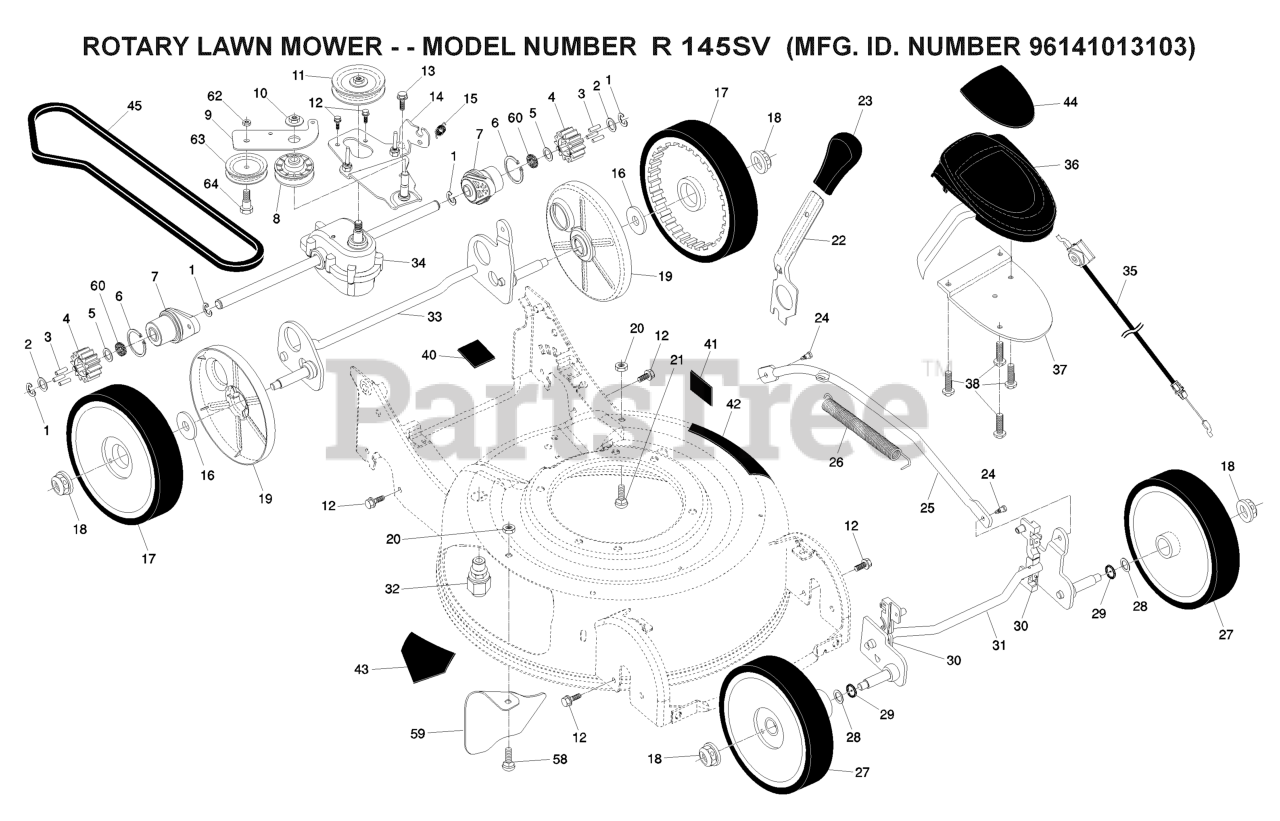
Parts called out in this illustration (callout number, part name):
1	E-RING 7/16 RE
2	THRUST WASHER
3	PAWL.DRIVE.ETCHED
4	PINION.DRIVE.WALK
6	RETAINING RING (2 2)(3 2)
7	BEARING.ASM
8	PULLEY.IDLER.V-BELT
9	ARM.IDLER.BZP
10	NUT.HEX.FLANGE.3/8-16.LOCKNUT
11	PULLEY.1.PIECE
13	SCREW 14-20 X 5/8
15	SPRING.RETURN
16	WASHER FLUT
17	WHEEL.8X1.75.H3SPK.RAD3.GY.BU3
18	NUT.HEX.FLANGE.3/8-16.LO(3 2)
19	COVER.DUST.WHEEL
20	NUT, HEX
21	BOLT.CARRIAGE.1/4-20 X 7/8
24	SHOULDER BOLT SEMI GIMLET PT.
25	ROD.LIFT.BZP
26	SPRING EXTENSION
27	WHEEL & TIRES ASSY, FRONT
28	WASHER.FLAT.1/2
29	O-RING..070X.487.NEOPRENE
30	BUSHING.FRONT.TORQUE.SHAFT
37	BRACKET.DRIVE.CONTROL.MOUNT.BL
38	SCREW, PHILLIPS HEAD 10 X 5/8
43	DECAL.INTERNATIONL.CUTFINGER
62	NUT.CENTERLOCK.5/16-
63	IDLER PULLEY
64	SHOULDER BOLT
